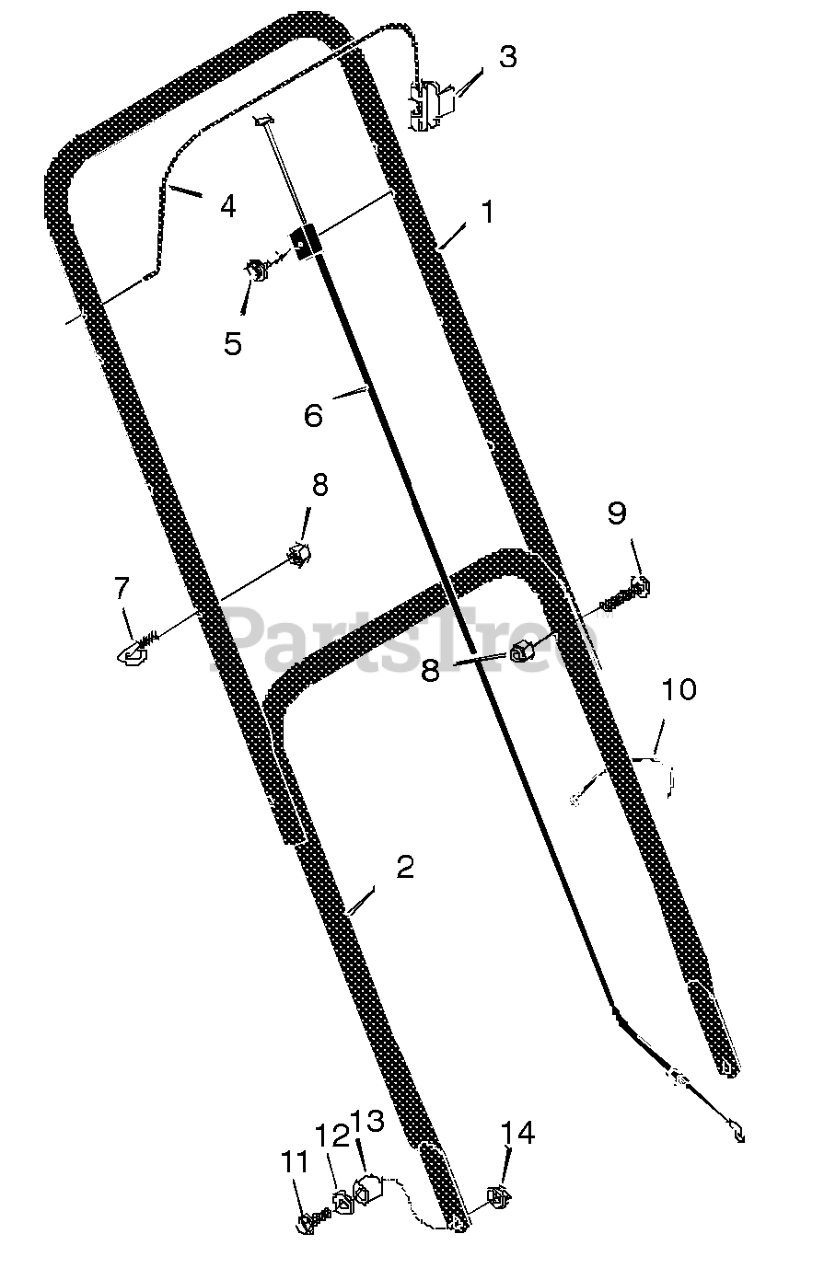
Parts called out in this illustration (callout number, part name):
1	Handle, Upper (Black)
2	Handle, Lower (Black)
3	Bracket, Stop Lever
4	Lever, Stop
6	Engine Stop Cable
7	GUIDE, ROPE
8	Locknut
10	Fastener, Cable
11	Bolt
14	Nut
